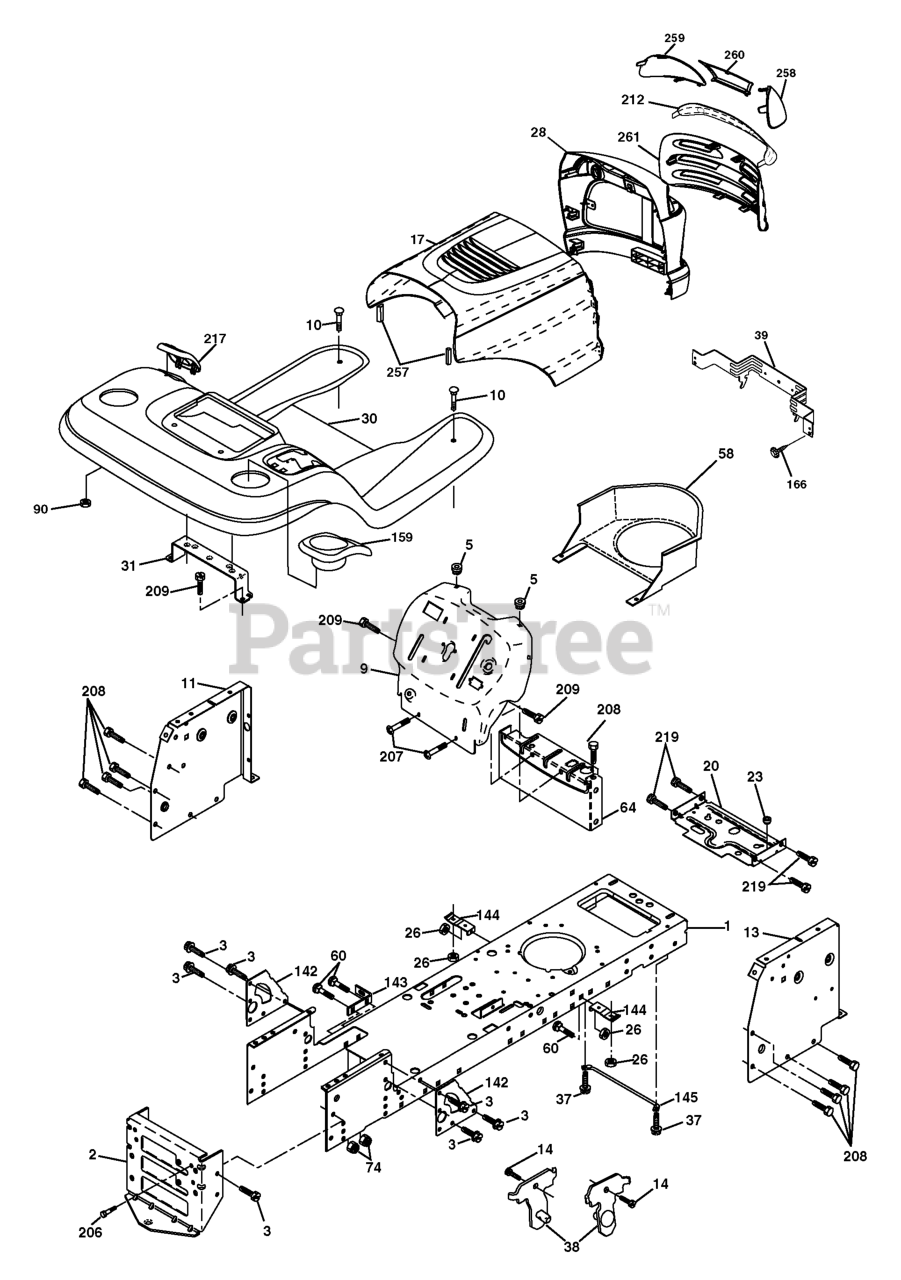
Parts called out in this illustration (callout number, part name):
1	CHASSIS STAMPING
2	DRAWBAR, 12GA
3	SCREW 3/8-16X3/4
5	BUMPER.RUBBER.HOOD
9	DASH SLKSCR
10	BOLT D
11	PANEL.DASH.LH.LTX
13	PANEL ASM, DASH RH
14	SCREW LT
17	HOOD
20	PLATE MTG.BATTERY/FUEL TANK
23	BUSHING.SNAP.NYL.BLK.
26	NUT
28	GRILL/LEN.ASM.DL.HUSQ
30	FENDER
31	BRACKET.SUPPORT.FENDER
37	Screw Thdrol 5/16-18 x 1/2
38	BRACKET.ASM.PIVOT.MOWER.REAR
39	BRACKET PIVOT LASER
60	Bolt RDHD SQNK 3/8-16 x 3/4
64	DASH LOWER
90	NUT.PUSH.3/16
142	PLATE REINFORCEMENT
143	BRACKET, SWAY BAR
144	BRKT, FOOT REST
145	ROD PIVOT CHASSIS/HOOD
159	GREY CUP HOLDER
166	SCREW
206	SHOULDER BOLT 5/16-18TT
207	SCREW, 5/16-18 X 1/2
208	SCREW 3/8-16X1/2
209	SCREW, 3/8-16X3/4
212	INSERT.LENS.REFLECTIVE
217	CONSOLE FUEL WINDOW
219	SCREW
257	BUMPER.HOOD.LARGE.1.75"
258	LENS LH
259	LENS LH
260	COVER.LENS.HUSQ.( HAVE GRAY)
261	INSERT GRILLE
